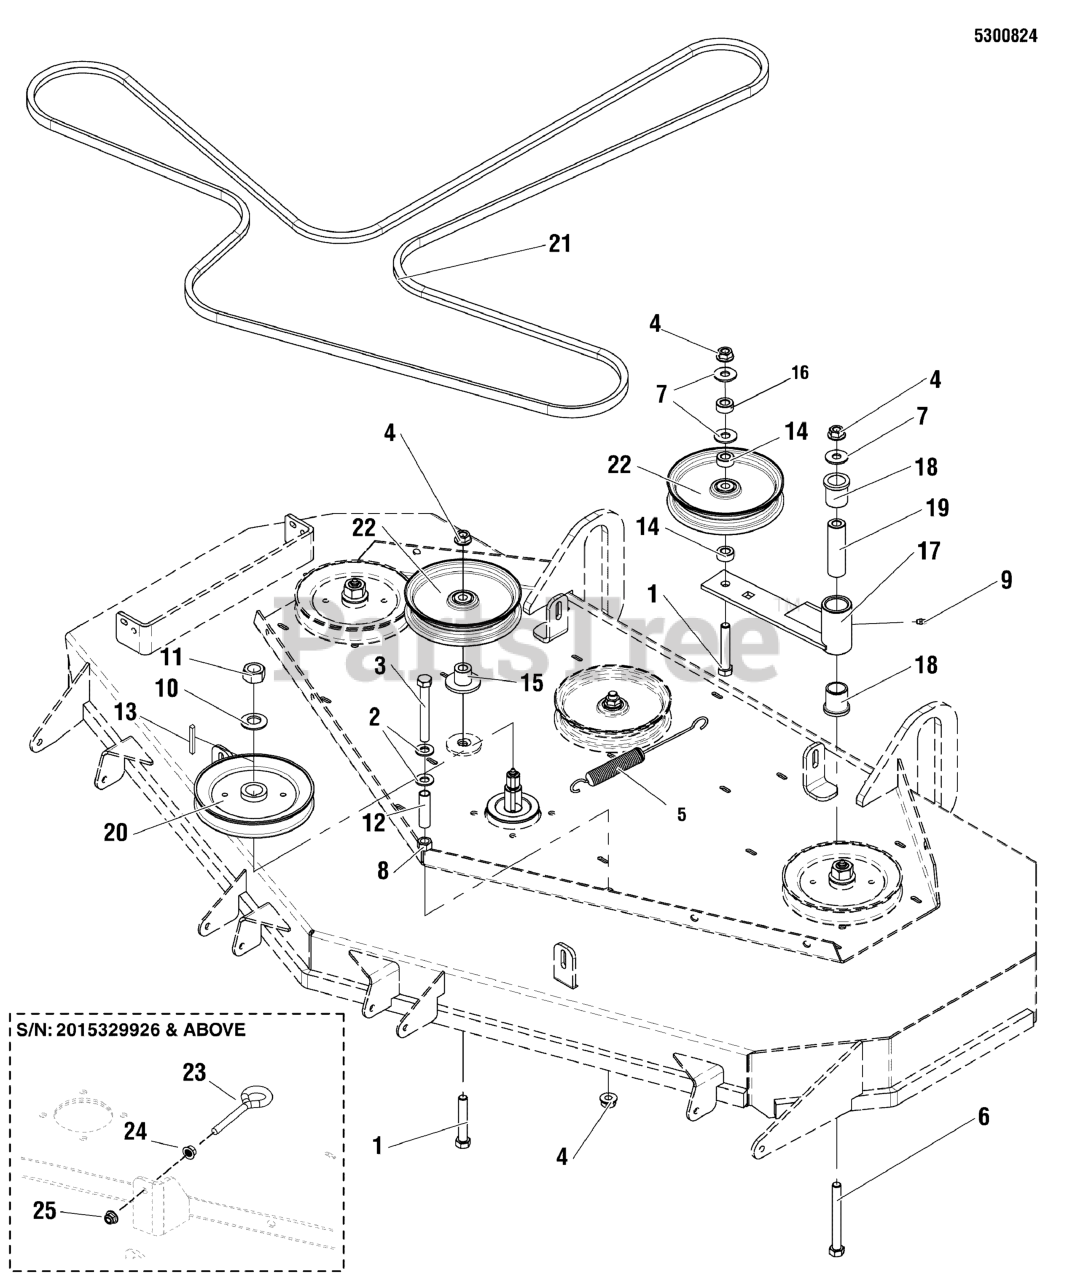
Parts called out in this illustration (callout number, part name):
1	BOLT, 1/2-13 X 3-1/4, HEX HD, GD5, CZ (SV)
2	WASHER, 1/2 SAE
3	BOLT, 1/2-13 X 4" GD5 CZ
4	NUT, Hex Flange, Nylock, 1/2-13
5	SPRING, EXTENSION, SWIVEL. LONG HOOK
6	BOLT, 1/2-13 X 4-1/2" GD5
7	WASHER, 1/2" USS
8	NUT, 1/2-13 HEX
9	GREASE FITTING, 1/4-28 STRAIGHT
10	WASHER, 3/4 BELLEVILLE
11	NUT, 3/4-16 HEX
12	HOSE, 1/2" PUSH-ON 2.25"
13	KEY, 1/4" SQ. X 1-1/4
14	SPACER, .52 X 1.00 X .56, CZ
15	IDLER MOUNT
16	SPACER, .52 X 1.00 X .22, PM, CZ
17	ASSM, IDLER ARM
18	BUSHING, FLANGE
19	SPACER, .52 X 1.00 X 3.50
20	PULLEY, 6.93 EOD X 25MM, SPLIT
21	BELT, 5V, 169.37"EL, ARAMID WRPD RC
23	EYE BOLT, 3/8-16 X 5, 2.88THRD, 1EYE, CZ
24	NUT, 3/8-16 HEX SERRATED FLANGE
25	NUT, 3/8-16 HEX NYLOCK FLANGE
